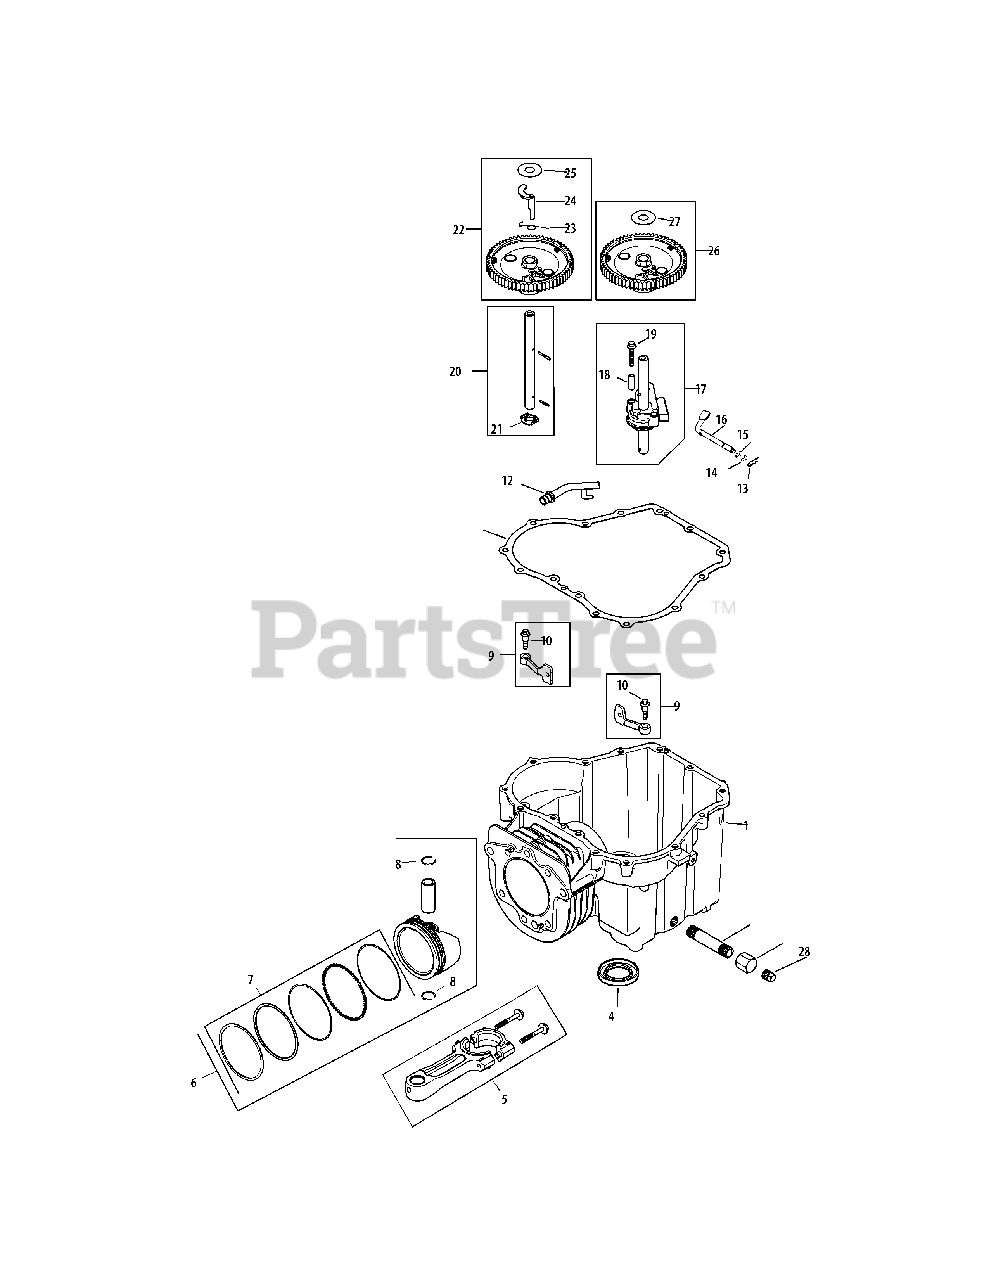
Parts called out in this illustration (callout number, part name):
1	Crankcase
4	Oil Seal
5	Connecting Assembly Rod
6	Piston w/ Ring Set, 94mm (Incl. 7, 8)
7	Ring Set (94mm)
8	Piston Pin Retainer
9	Cam Lever Ass. Kit (Incl. 10)
10	Shd. Thd. Frm. Screw, M6 X 1 X 26
12	Drainback Tube
13	Hitch Pin Clip
14	Flat Washer, 6 Mm
15	Flat Washer, 1/4
16	Governor Cross Shaft
17	Oil Pump Ass’y Kit (Incl. 11, 18, 19)
18	Oil Pump Screw Spacer
19	Oil Pump Screw
20	Cam Center Shaft Kit (Incl. 21)
21	Thrust Washer
22	Camshaft Ass’y Kit (Incl. 23-25)
24	Acr. Weight
25	Thrust -Acr. Washer
26	Camshaft Ass’y Kit (Incl. 27)
27	Thrust -Acr. Washer
28	Square Head Pipe Plug, 3/8
